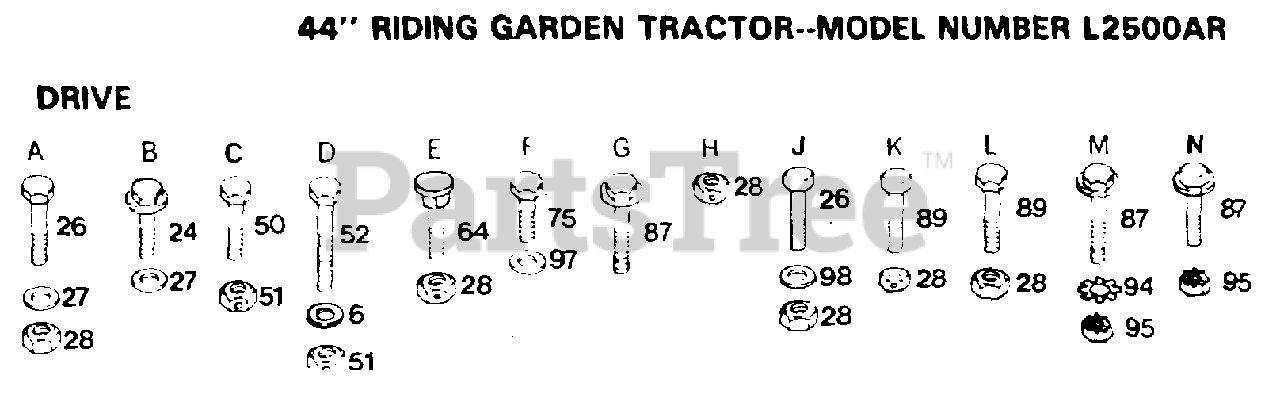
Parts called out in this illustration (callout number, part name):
6	WASHER
24	SCREW
26	BOLT
27	WASHER
50	BOLT
64	BOLT
75	SCREW
87	SCREW LT
94	LOCKWASHER
95	NUT
97	WASHER
98	WASHER
